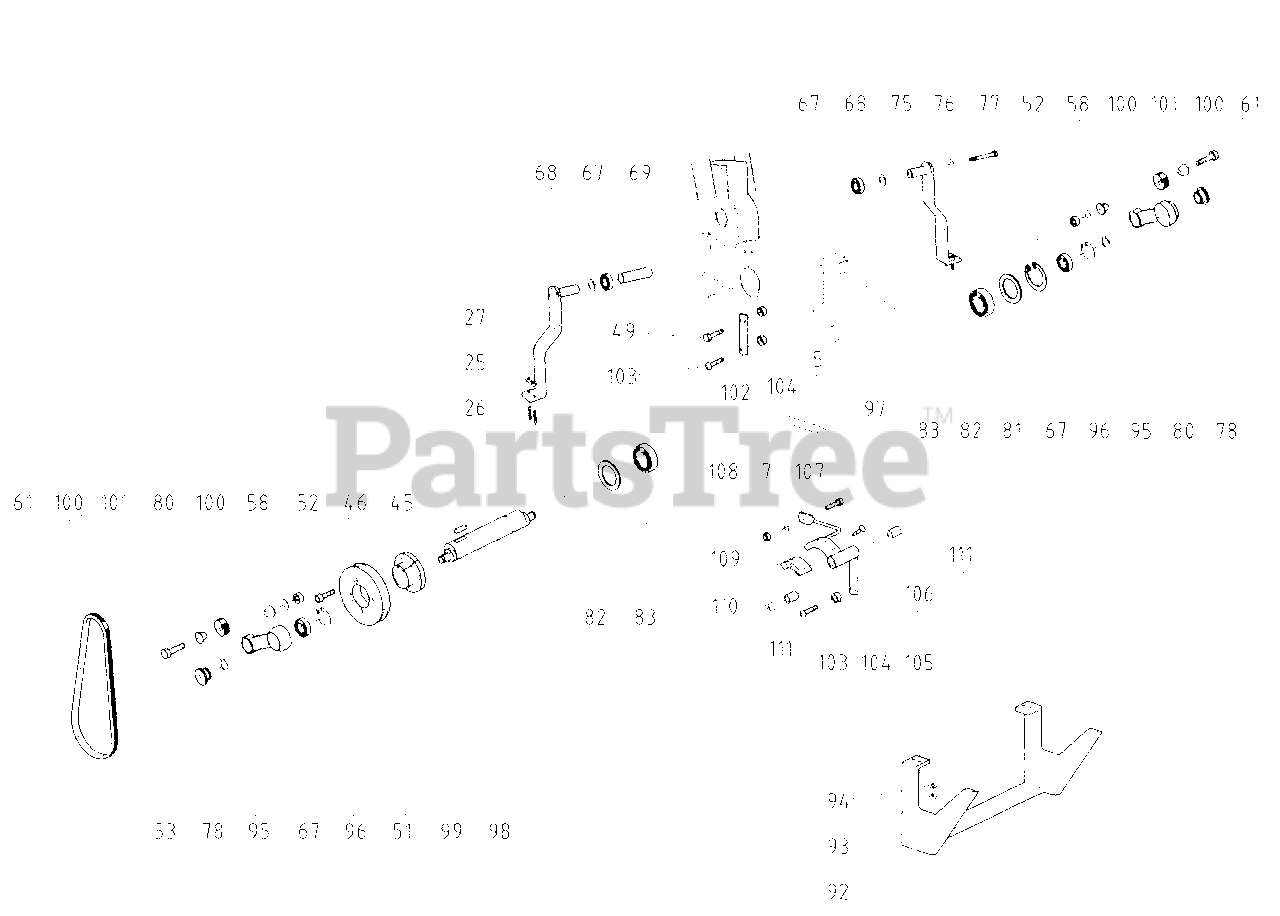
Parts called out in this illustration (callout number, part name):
5	Nut Lock M6 H6
7	Washer Flat M6
25	Nut M8 H5
26	Washer Grower
27	Arm Control Blade (Righthand)
45	Key 8x7x25
46	Screw Allen M6 x 25
49	Screwcap M6 x 14
51	Pulley for shaft with eccentrics
53	Belt Short XDV48/290
58	Washer Flat M12x24
61	Screw Special
67	Bearing 17x40x12 6203-2RS
68	Shim adjustment 17x24x0.5
75	Arm control Blade (lefthand)
76	Washer Split M6
77	Screwcap M6x85 P.F.
78	Cover Plastic Connecting Rod
80	Rod Connecting
81	Ring Snap Internal E35
82	Shim adjustment 35x45x0.5
83	Bearing 35x62x14 6007-2RS
92	Blade Cutting
93	Screw M8 x26
94	Washer Wave M8
95	Ring Snap Internal E17
96	Ring Snap Internal 140
98	Shaft with eccentrics
99	Pulley locking hub
100	Semi-cone
101	Pad Rubber
102	Spring Hook
103	Screw Button M6 X 16
104	Nut M6 H4
106	Screwcap M4 X 14
107	Clamp 7 X 20
109	Pad Brake
110	Ring Radial elastic D 10
111	Bushing Self Lock
